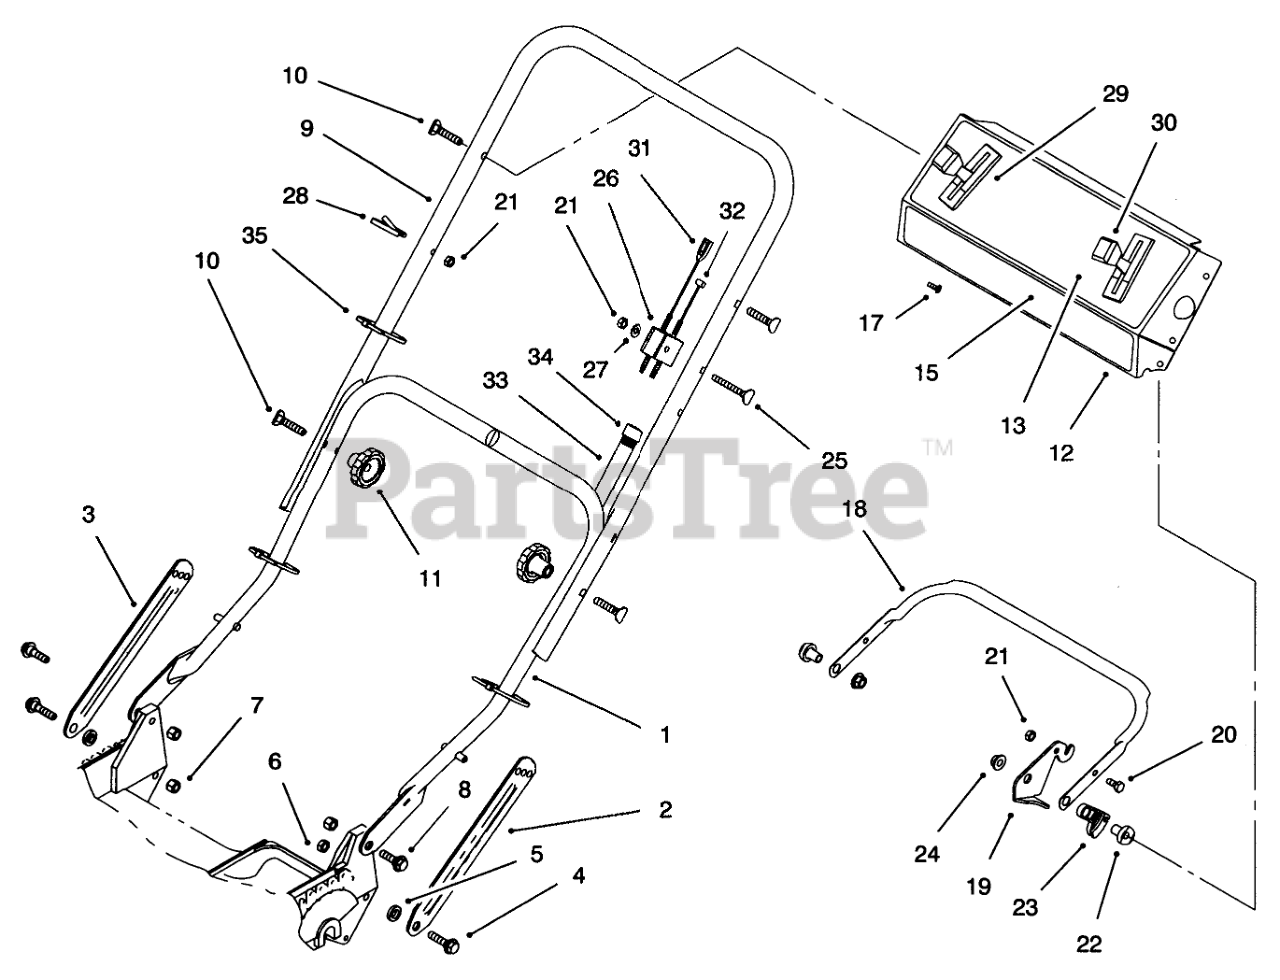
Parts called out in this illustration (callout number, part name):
1	ASM-Handle
2	Latch-Handle
3	Latch-Handle
4	SCREW-SHOULDER
5	SPACER
6	NUT-LOCK, NI
7	NUT-LOCK, NI
8	SCREW-SHOULDER
9	Handle-Upper
10	SCREW-HANDLE
12	Panel-Control (Incl. Ref. #13)
13	DECAL - INSTRUCTION
15	DECAL - CONSOLE
17	SCREW-TAP
18	Bar-Control
19	Lever-Control
20	SCREW-HH
21	NUT-LOCK, NI
22	SPACER-SUPPORT
23	LEVER-TRACTION
24	NUT-LOCK NI
25	SCREW-HANDLE
26	SUPPORT-CABLE
27	WASHER-FLAT
28	GUIDE-ROPE
29	CONTROL-SPEED, GROUND
30	CABLE - THROTTLE
31	CABLE - BRAKE
32	CABLE-TRACTION
33	CONTROL CABLE COVER
34	FITTING-RING
35	TIE-CABLE
